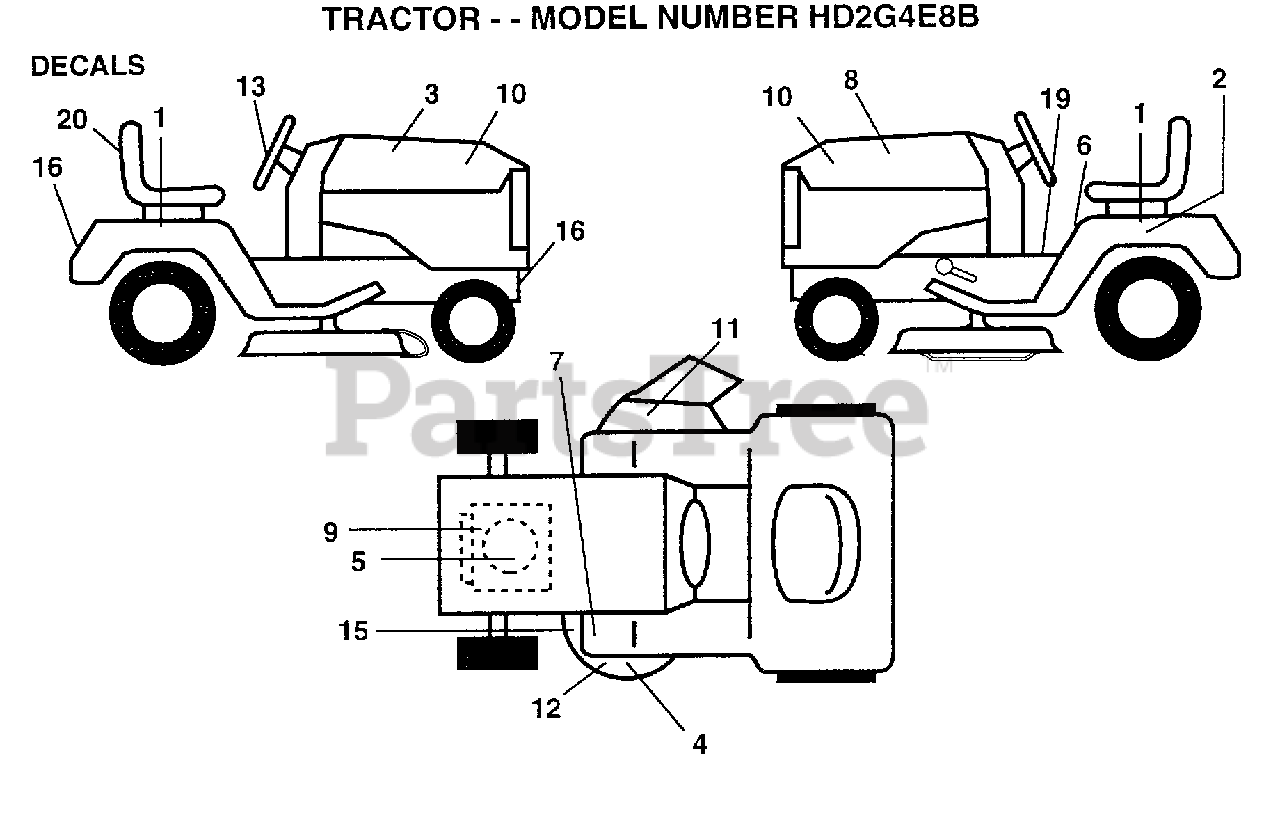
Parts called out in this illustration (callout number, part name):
1	DECAL.FEND.QUICKS
2	DECAL.BTRY.DANGER
3	DECAL.HD.RH.12.5
4	DECAL.DECK.MULCH.
5	DECAL, ENGINE
6	DECAL CAUT FEND
7	DECAL CLUT/BRAKE
8	DECAL.HD.LH.12.5
9	DECAL.PARTS.B&S.
10	DECAL.PNL.SD.HDPO
11	"DECAL, WARNING"
12	DECAL.SCH.PRIM.42
13	DECAL.INST.WHL.ST
15	DECAL.SCH.DRV.42
16	DECAL.FENDER.HDEP
19	DECAL.SADDLE.INST
20	DECAL.SEAT.HDPT.
